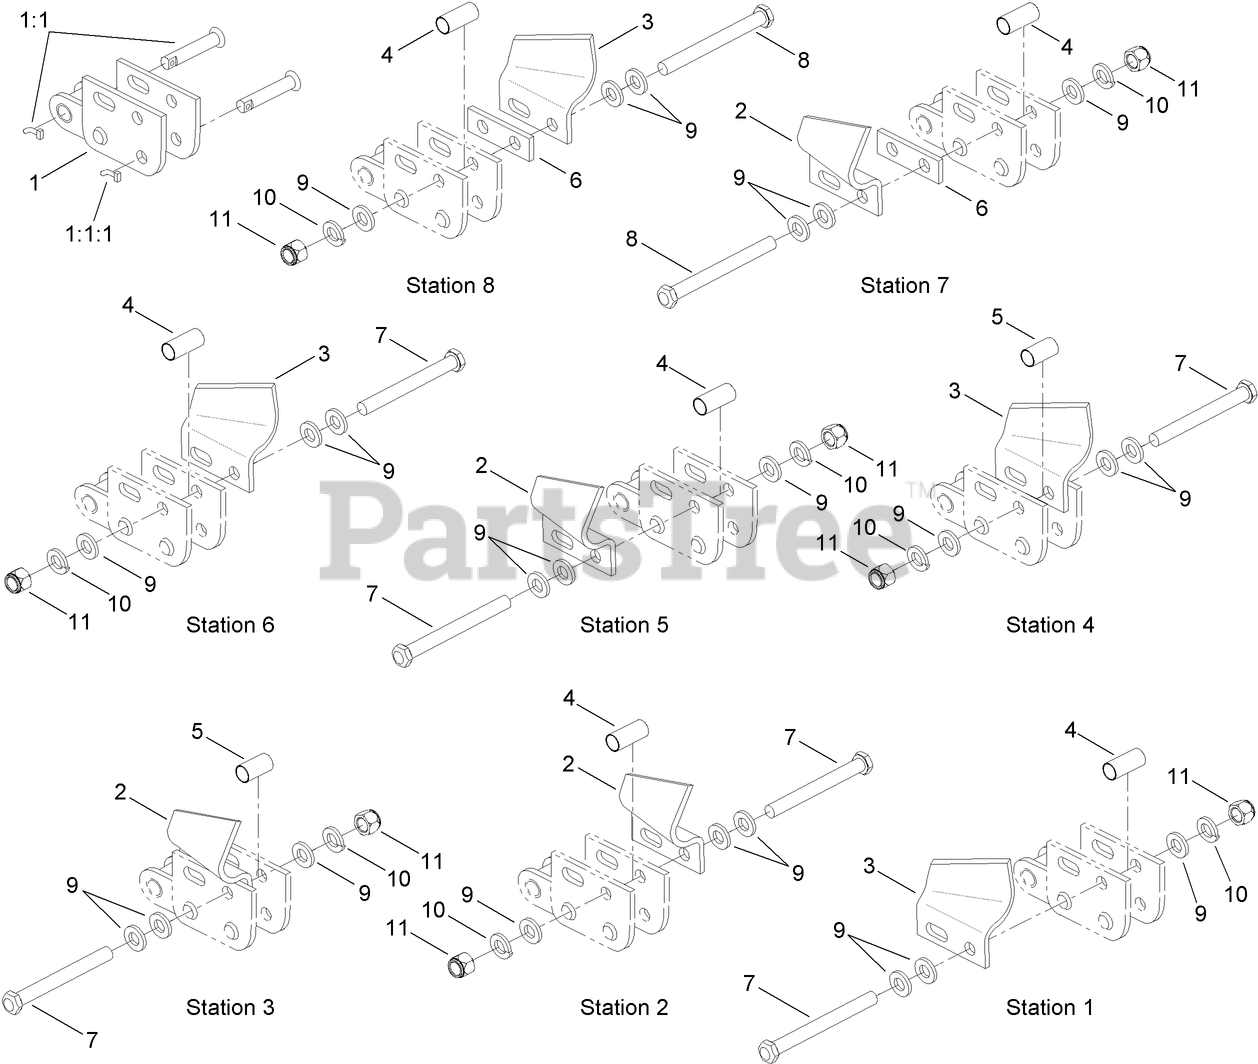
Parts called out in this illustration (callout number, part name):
1	CHAIN REPAIR LINK ASM
1:1	NOTCHED PIN AND KEEPER ASM
1:1:1	PIN-KEEPER
2	CUTTER-CUP, RH
3	CUTTER-CUP, LH
4	SPACER-TUBE, OUTSIDE MOUNT
5	SPACER-TUBE, INSIDE MOUNT, CUP
6	SPACER-FLAT
7	BOLT-HH
8	BOLT-HH
9	WASHER-FLAT
10	WASHER-LOCK
11	NUT-LOCK
